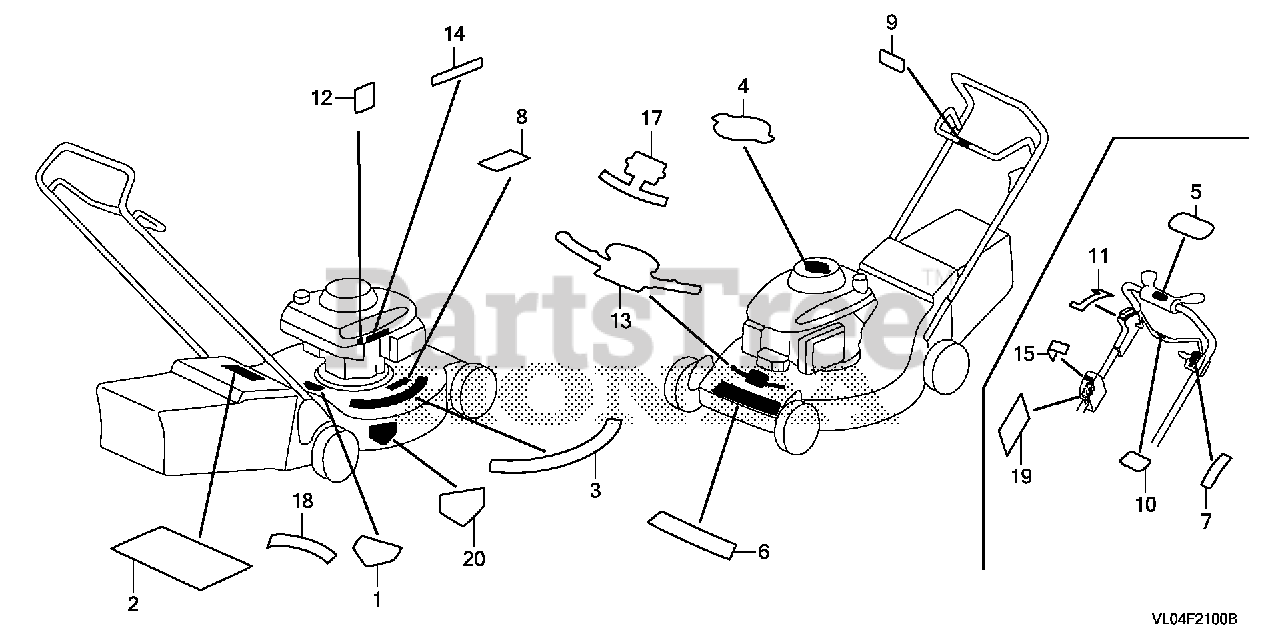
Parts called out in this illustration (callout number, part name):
1	CAUTION C, HOUSING
2	LABEL, WARNING (ENGLISH)
3	MARK (VARIABLE SPEED)
4	MARK, RECOIL COVER
5	MARK, CLUTCH INDICATION (ENGLISH)
6	MARK, HONDA
7	MARK, THROTTLE INDICATION (ENGLISH)
8	LABEL, HEAT WARNING
10	MARK, BLADE CONTROL (ENGLISH)
11	MARK, ROTO-STOP CONTROL (ENGLISH)
12	MARK, OIL CAUTION
13	MARK, SALES POINT (QUADRA CUT SYSTEM)
14	MARK, OIL RECOMMENDED
